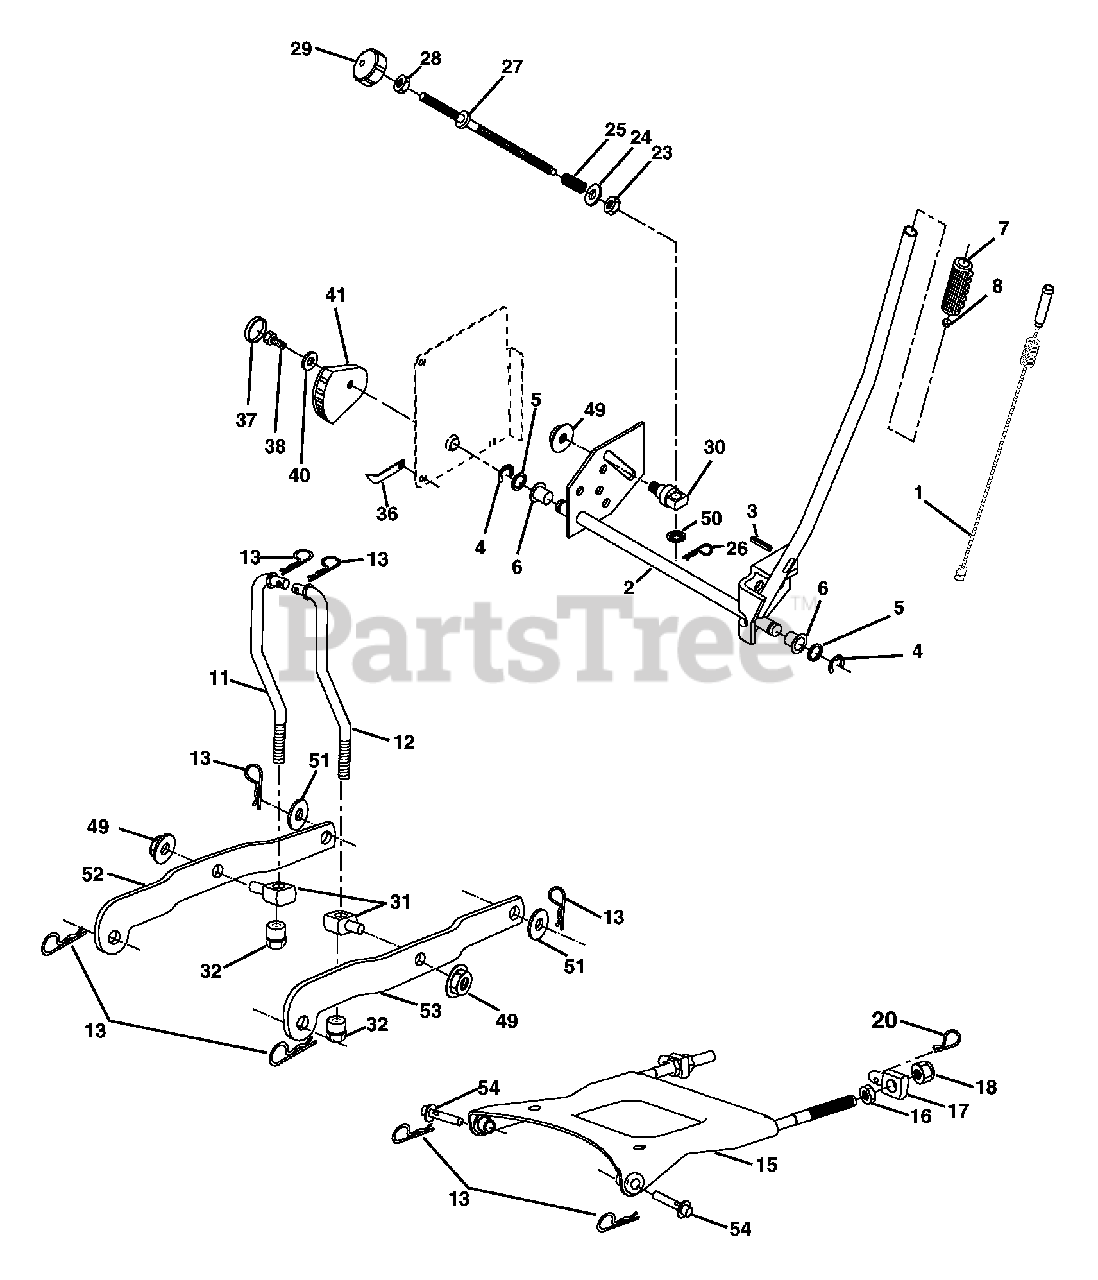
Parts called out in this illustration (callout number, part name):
1	Plunger Asm.
2	Shaft Asm Lift RH w/Inf
3	Pin Groove
4	E Ring #5133-62
5	Washer 21/32 x 1 x 21 Ga.
6	Bearing Nylon Blk 629 Id
7	Grip Handle
11	Link Lift LH
12	Link Lift RH
13	Retainer Spring
15	Plate Asm. Suspension Front
16	Nut Jam Hex 1/2-13 unc
17	Trunnion Front Susp.
18	Nut Lock w/Wsh 1/2-13 unc
20	Retainer Spring
23	Nut Special
24	Washer 13/32 x 5/8 x 16 Ga.
25	Spring Infin, Height
26	Retainer Clip
27	Rod Adjust Lift
28	Nut Hex Jam 3/8-16 unc
29	Knob Infin. Height
30	Trunnion Infin, Height
31	Trunnion Susp. Arm
32	Nut Lift Link 7/16-20
49	Nut Hex Flange Lock
50	Nut Push
51	Washer 17/32 x 7/8 x 16 Ga
52	Arm Susp. Rear LH
53	Arm Susp. Rear RH
54	Pin
